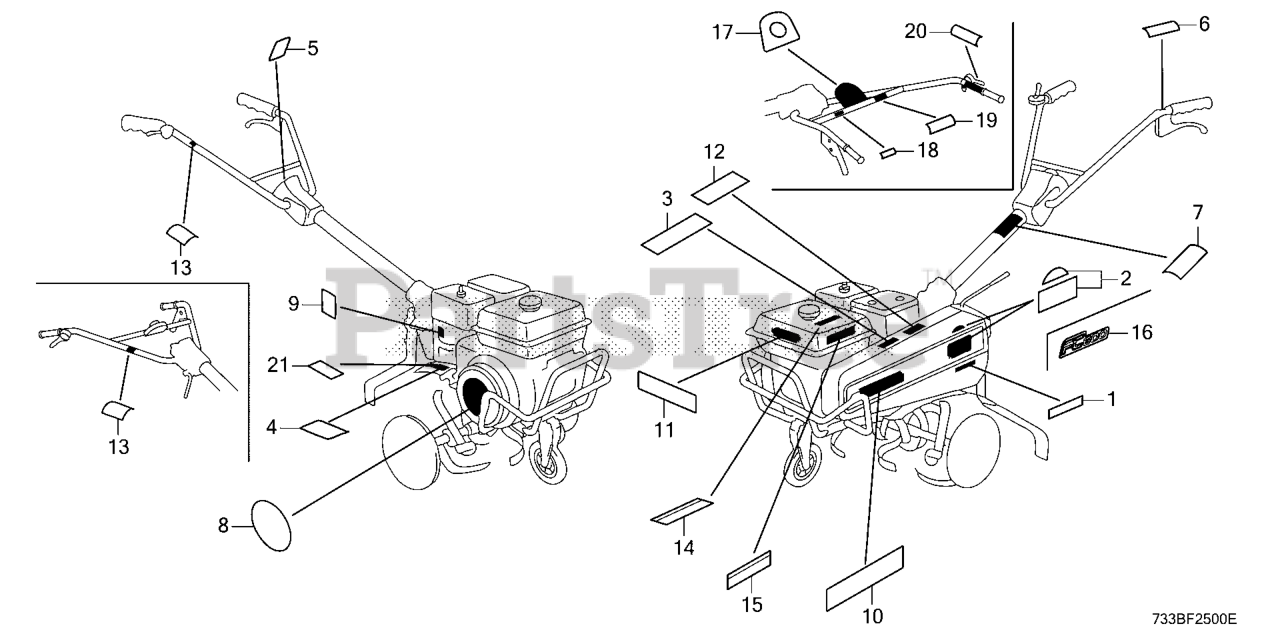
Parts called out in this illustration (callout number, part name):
3	LABEL, BELT COVER CAUTION (ENGLISH)
4	LABEL, TINE DANGER (ENGLISH)
7	LABEL, OPERATOR WARNING (ENGLISH)
8	EMBLEM (GX160)
9	MARK, CHOKE
10	MARK, HONDA
11	MARK, HONDA
12	LABEL, EX. CAUTION (ENGLISH)
13	MARK, HOLD POSITION
15	LABEL, SPARK WARNING
16	MARK, BELT COVER EMBLEM
17	MARK, ENGINE SWITCH (ENGLISH)
18	MARK, CLUTCH INDICATION
20	MARK, THROTTLE INDICATION
21	LABEL, WARNING
